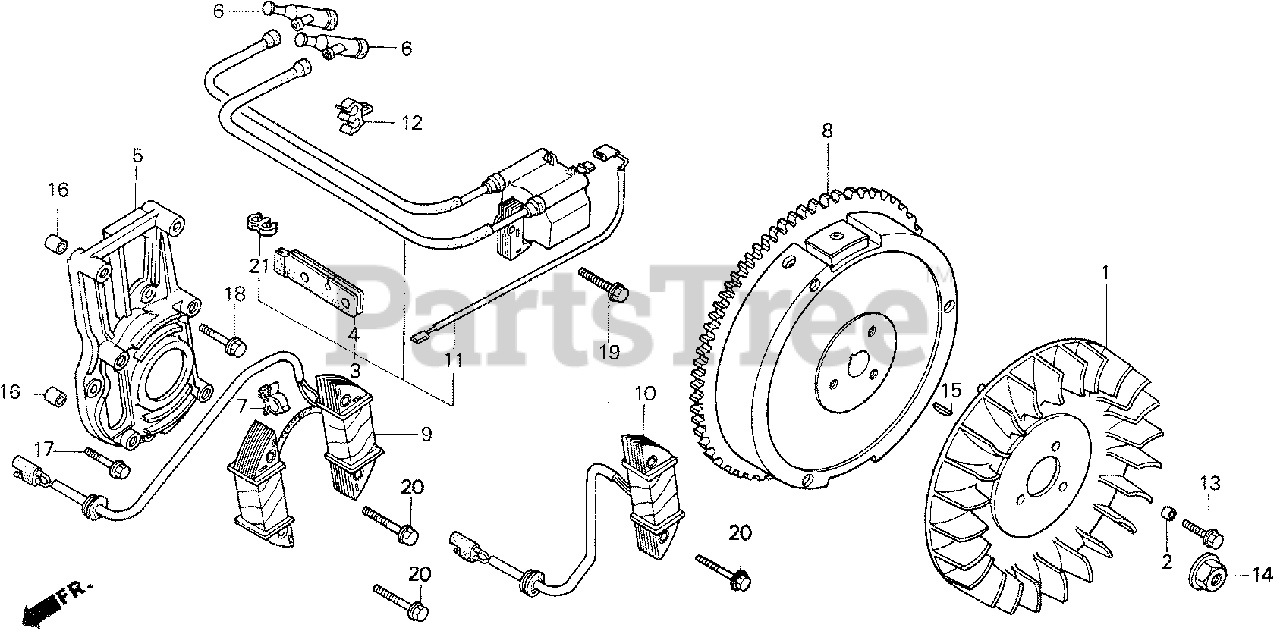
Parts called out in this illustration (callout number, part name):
1	FAN, COOLING
2	COLLAR, FAN
3	COIL ASSY., IGNITION
4	GROMMET, IGNITION WIRE
5	STAY, IGNITION SYSTEM
6	CAP ASSY., NOISE SUPPRESSOR
7	CLIP, IGNITION WIRE (8MM)
8	FLYWHEEL
9	COIL ASSY., CHARGE (10A)
11	WIRE, ENGINE STOP
12	CLIP, RECEIVER PIPE
13	BOLT, FLANGE (6X16)
14	NUT, SPECIAL (16MM) (1)
14	NUT, SPECIAL (16MM)
15	KEY, SPECIAL WOODRUFF (25X18)
16	PIN A, DOWEL (8X10)
17	BOLT, FLANGE (6X22)
18	BOLT, FLANGE (6X28)
19	BOLT, FLANGE (6X28)
20	BOLT, FLANGE (6X32)
